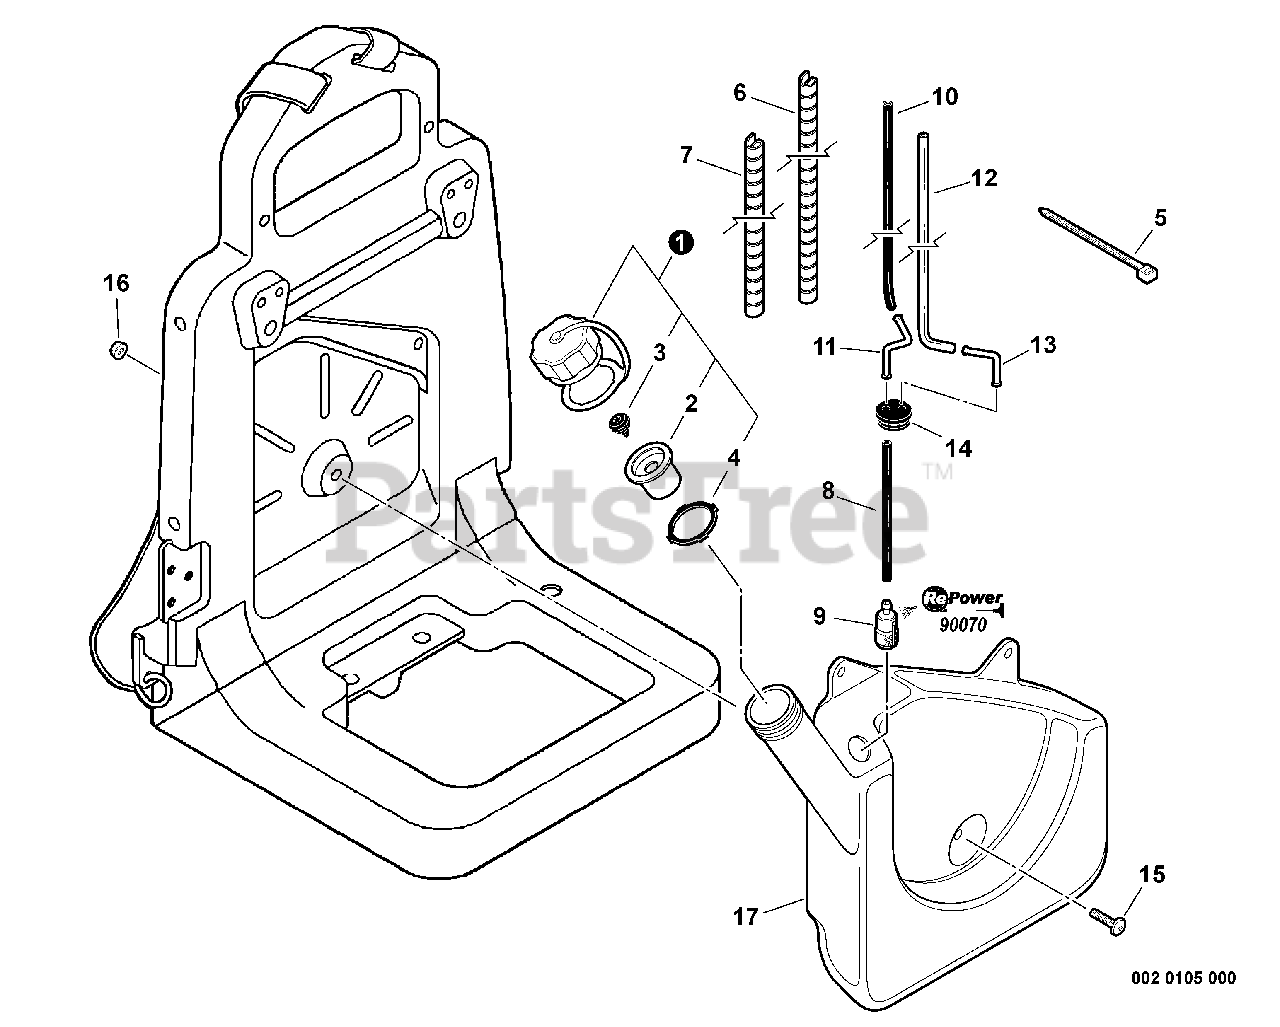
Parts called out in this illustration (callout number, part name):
1	CAP ASSY
2	HOLDER, CHECK VALVE
3	VENT ASSY
4	GASKET, FUEL CAP
5	TIE, CABLE
6	WRAP, SPIRAL
8	PIPE, FUEL 3×6×280 MM
9	FILTER, FUEL
10	PIPE, FUEL
11	CONNECTOR, PIPE
12	PIPE, FUEL
13	CONNECTOR, PIPE
14	GROMMET
15	SCREW 5×20
16	NUT, LOCK M5
17	TANK, FUEL
18	TUNE-UP KIT - REPOWER
